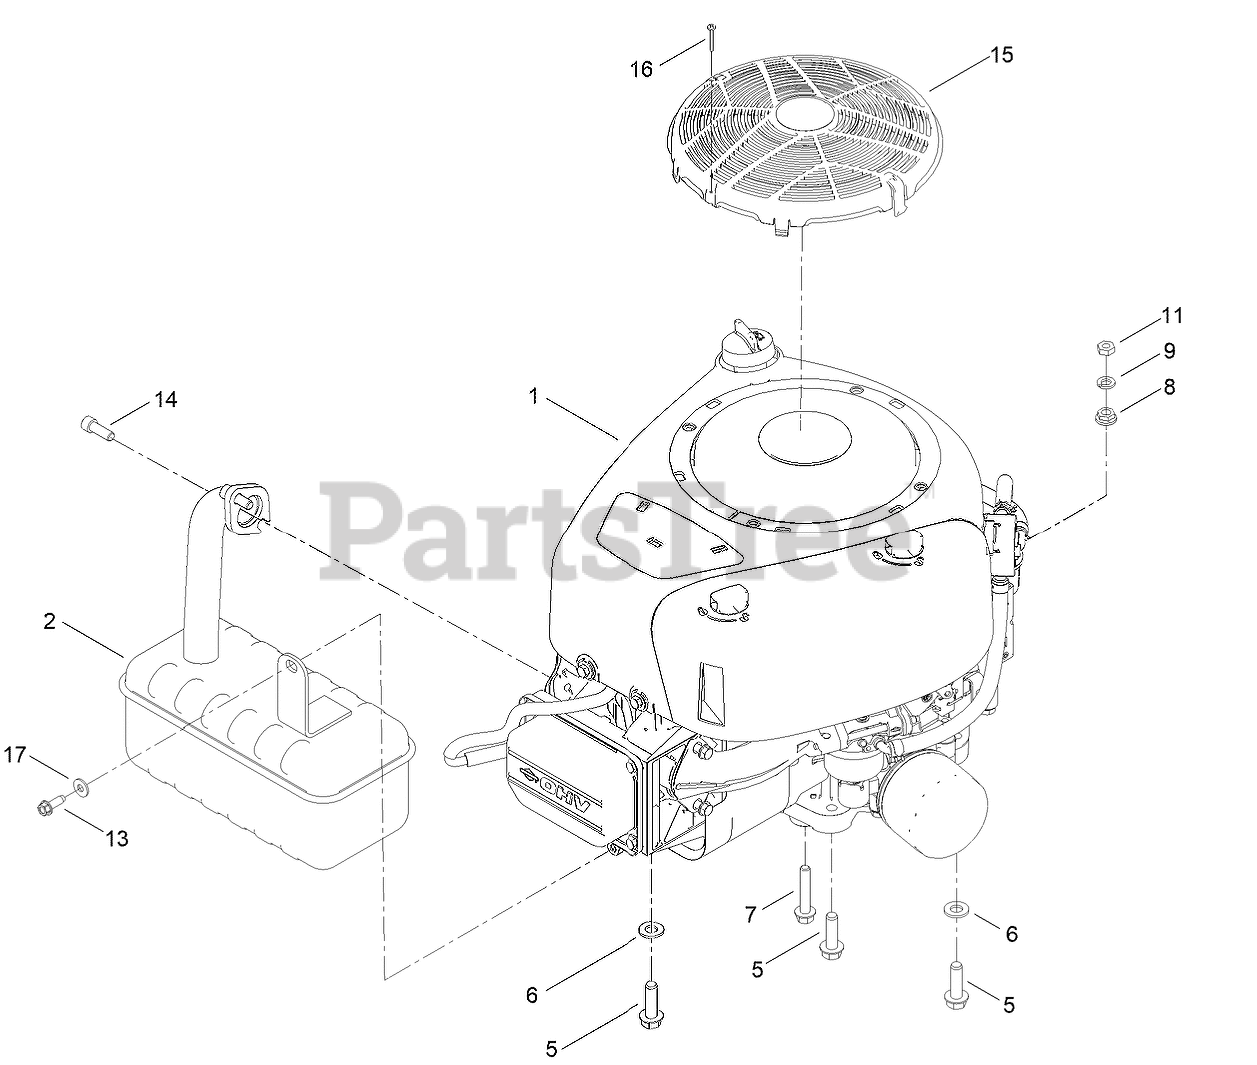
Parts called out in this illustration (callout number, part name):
1	ENGINE-BS PROFESSIONAL
2	MUFFLER
5	SCREW-THD
6	WASHER-FLAT
7	SCREW-HWH
8	NUT-HF
9	WASHER-LOCK
11	NUT-JAM
13	SCREW-HWHTF
14	SCREW-HSH
15	COVER-FAN
16	SCREW-FAN
17	WASHER
